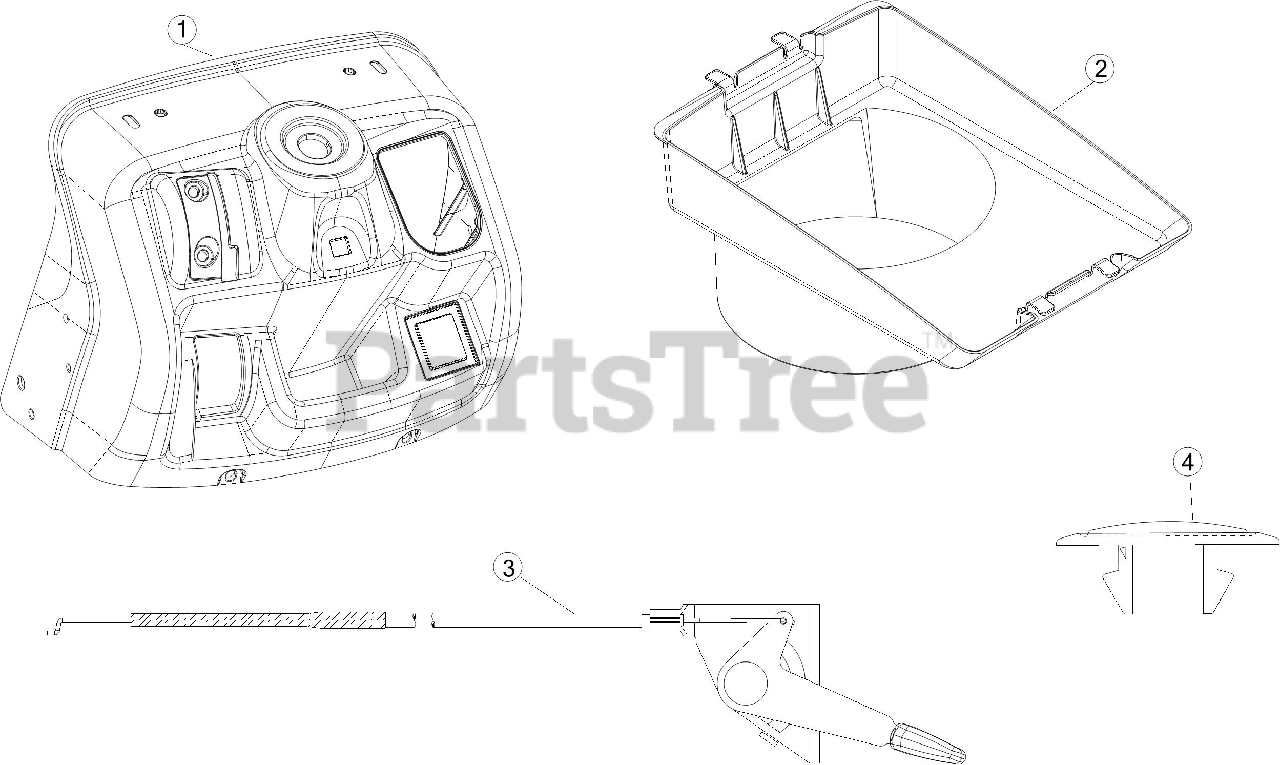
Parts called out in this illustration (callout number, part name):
1	UPPER DASH
2	HOOD PLENUM
3	THROTTLE CABLE 28" x 1.1
4	CHOKE PLUG
